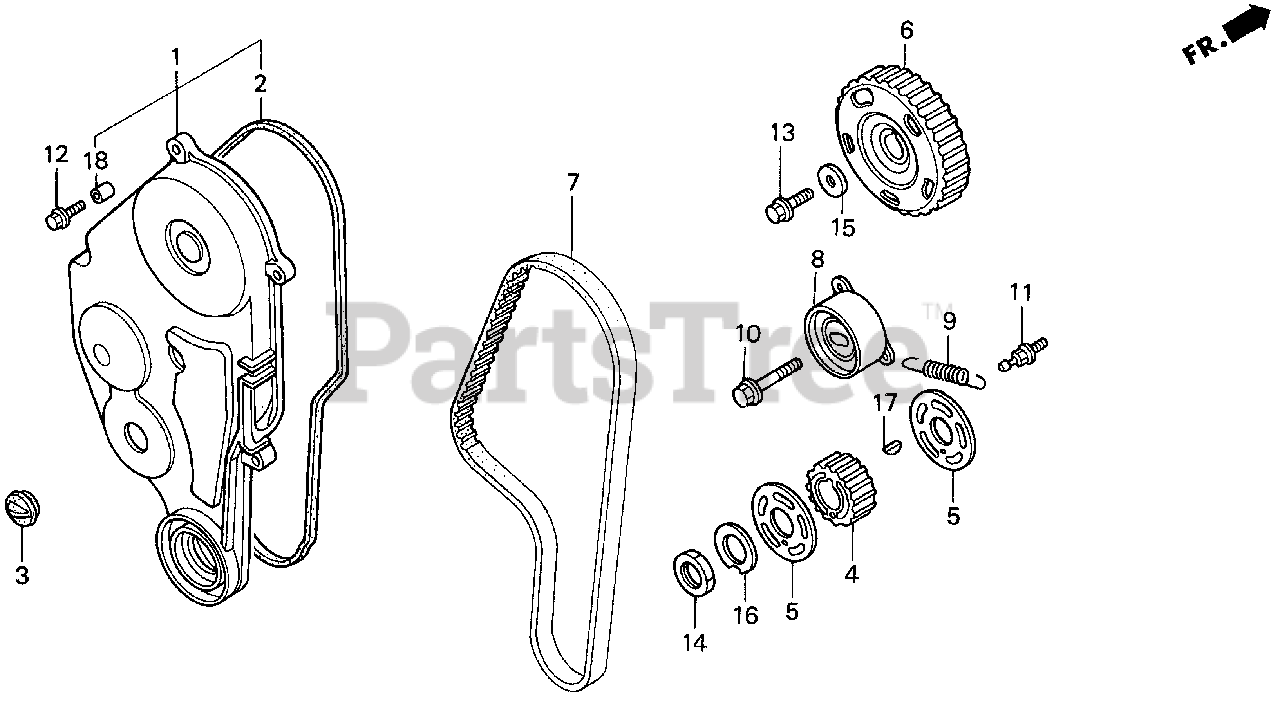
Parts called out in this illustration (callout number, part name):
1	COVER, TIMING BELT
2	GASKET, TIMING BELT COVER
3	GROMMET, TIMING BELT COVER
4	PULLEY, TIMING BELT DRIVE
5	PLATE, TIMING BELT GUIDE
6	PULLEY, TIMING BELT DRIVEN
7	BELT, TIMING
8	TENSIONER, TIMING BELT
9	SPRING, TIMING BELT ADJUSTING
10	BOLT A, TENSIONER
11	BOLT, TIMING BELT ADJUSTER SPRING (NAGOYA RASHI)
12	BOLT, FLANGE (6X20) (CT200)
13	BOLT, FLANGE (8X22)
14	NUT, LOCK (27MM)
15	WASHER, SPECIAL (28X8.5X4.0)
16	WASHER, LOCK (6MM)
17	KEY, SPECIAL (16X15)
18	COLLAR, CONTROL LEVER
